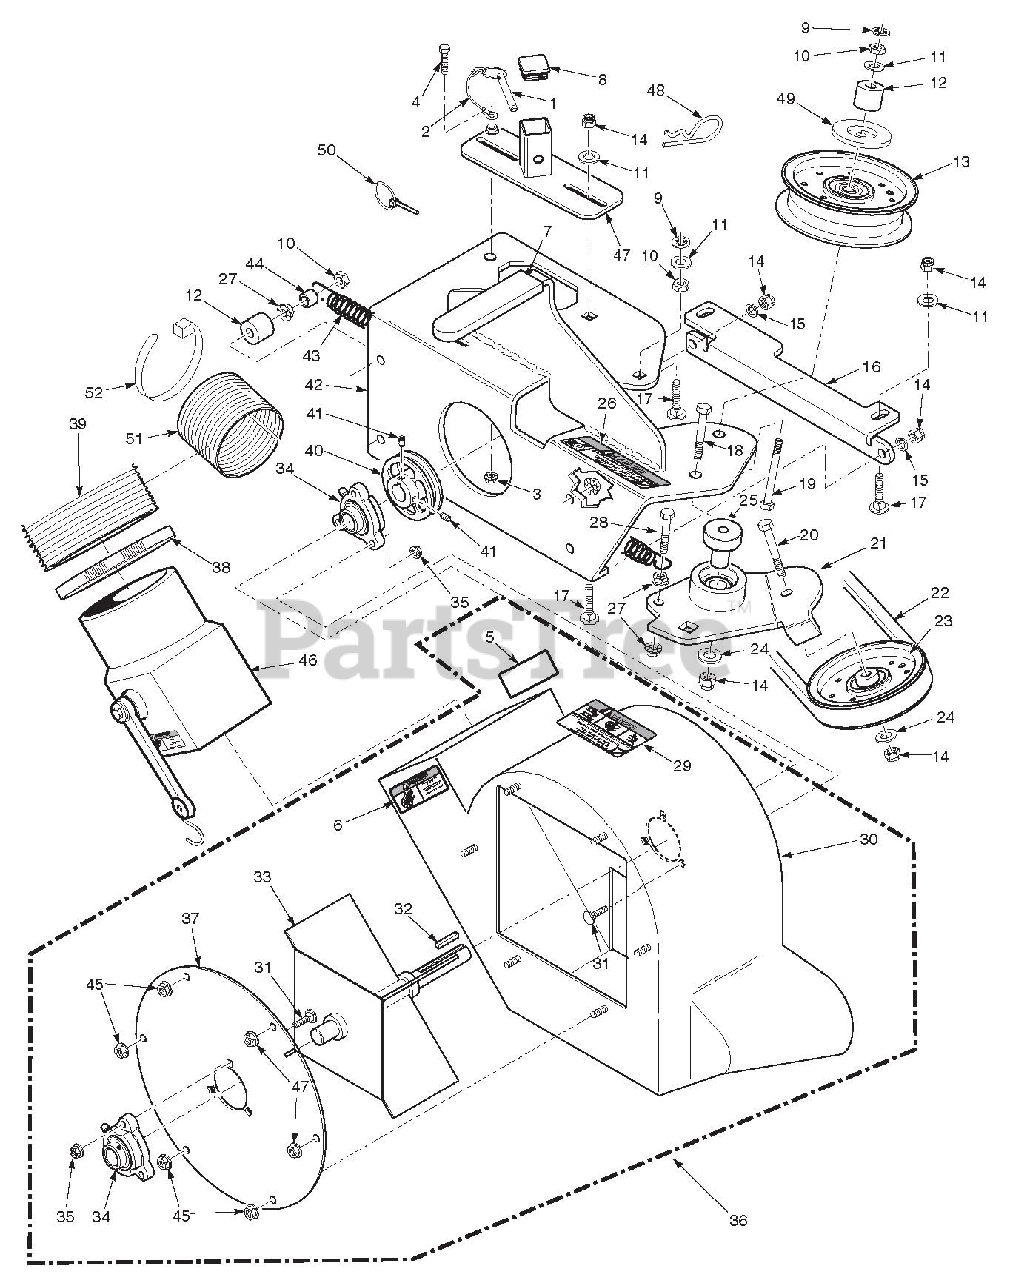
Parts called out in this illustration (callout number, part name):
1	Pin, Ring 2-1/4" Long
2	Lanyard, Deck Height Pin
3	Nut, Serr. Flange 1/4-20
4	Bolt, Hex Head 1/4-20 x 1-1/4"
5	Decal, Blower
6	Decal, Rotating Blower
7	Grip, Blower Lever
8	Cap, Square
9	Nut, Push On 3/8 Thread
10	Lock Nut, 3/8-16
11	Flatwasher, 3/8-.391 x .938 x .105
12	Spacer
13	Pulley, Idler 3-1/2" Dia.
14	Nut, Elastic Stop 3/8-16
15	Lockwasher, 3/8-16
16	Plate, Catcher Mounting
17	Bolt, Carr. 3/8-16 x 1-1/2"
18	Bolt, Hex Head 3/8-16 x 3" - 52"
19	Bolt, Hex Head 3/8-16 x 3-1/2"
20	Bolt, Hex Head 3/8-16 x 1-3/4"
21	Idler Arm Assembly
22	Belt, GC-SCZ-48V / STCII-48V
22	Belt, GC-SCZ-52V / STCII-52V
23	Pulley, 3-1/2" O.D.
24	Washer, 3/8 Hardened
25	Pivot, Idler
26	Decal, Belt Cover
27	Nut, Serr. Flange 3/8-16
28	Bolt, Hex Head 3/8-16 x 1-1/2 Gr. 8
29	Decal, Danger
30	Blower Housing Weldment
31	Bolt, Carr. 5/16-18 x 3/4" Gr. 5
32	Key, 1/4 x 1/4 x 1-1/2"
33	Fan Weldment
34	Bearing Assembly
35	Nut, Elastic Stop 5/16-18
36	Blower Housing Assembly
37	Cover, Blower Housing
38	Clamp, 8-5/8" Max Dia.
39	Hose, 8.00" Dia. x 53" Long
40	Pulley, 4-3/4" O.D. - 1" Bore
41	Set Screw, 5/16-18 x 3/8"
42	Frame, Blower Mount
43	Spring, Main Drive
44	Spacer
45	Nut, Serr. Flange 5/16-18
46	Adapter w/Strap
47	Receiver Weldment, Mounting Post
48	Hair Pin Cotter, .177 x 3-1/4"
49	Dust Shield
50	Quick Pin, 5/16" Dia.
51	Hose, 8" Dia. x 24" Split
52	Cable Tie, .345 X 31.5 Black
